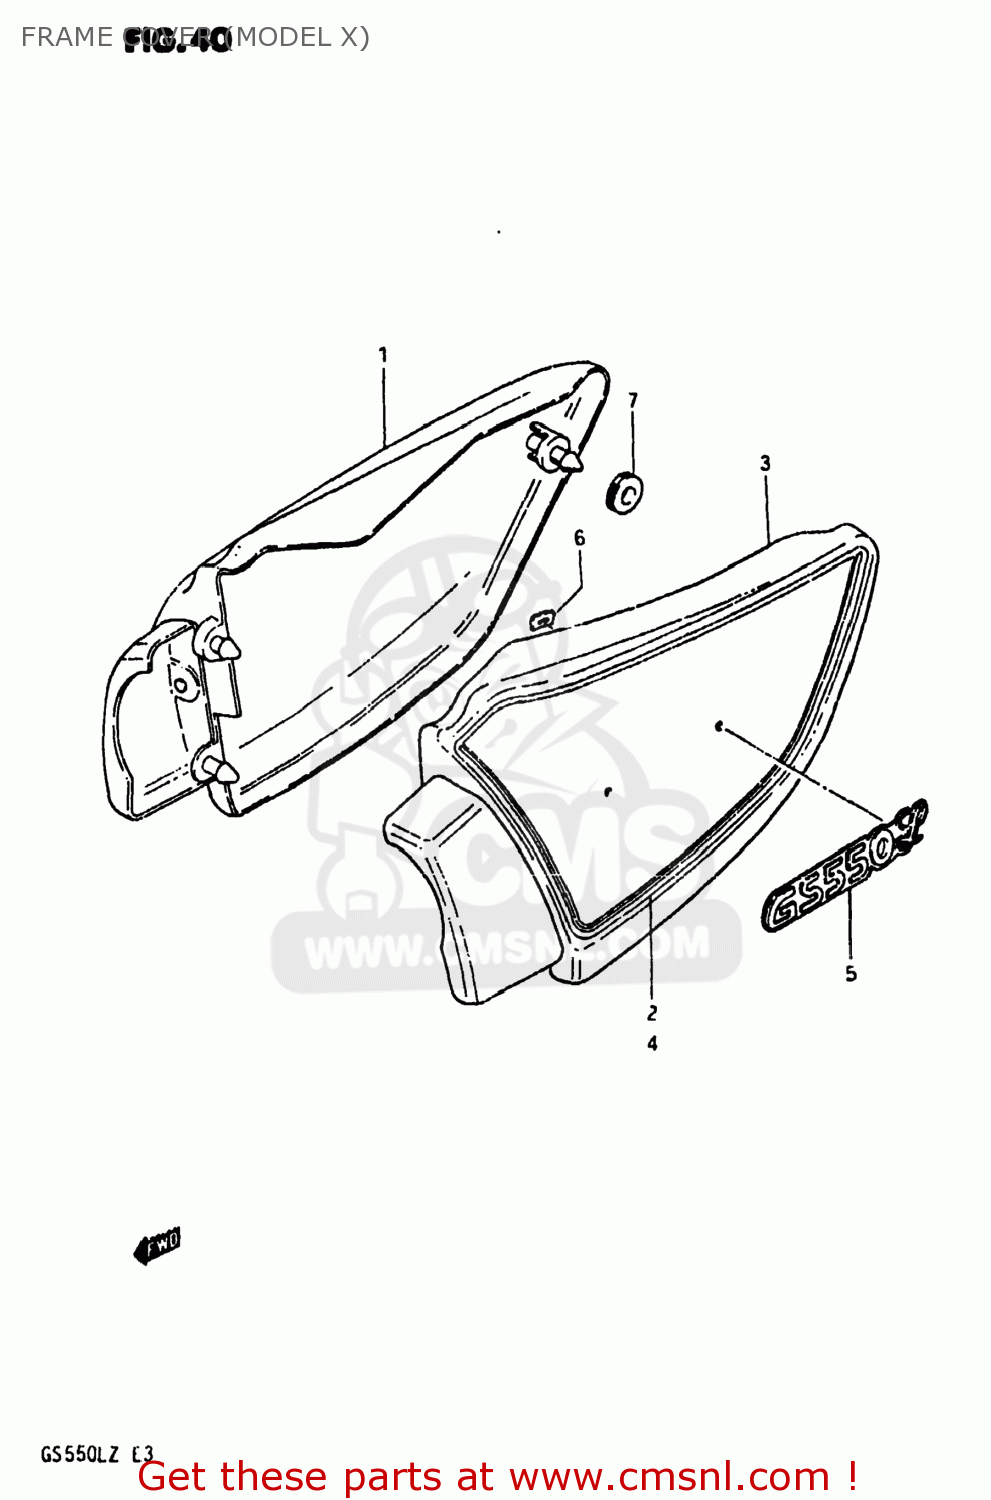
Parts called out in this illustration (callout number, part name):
1	COVER,FRAME,RIGHT
2	TAPE SET,FRAME COVER
3	COVER ASSEMBLY,FRAME,LEFT
4	TAPE SET,FRAME COVER
5	EMBLEM,FRAME COVER
6	NUT
7	CUSHION
